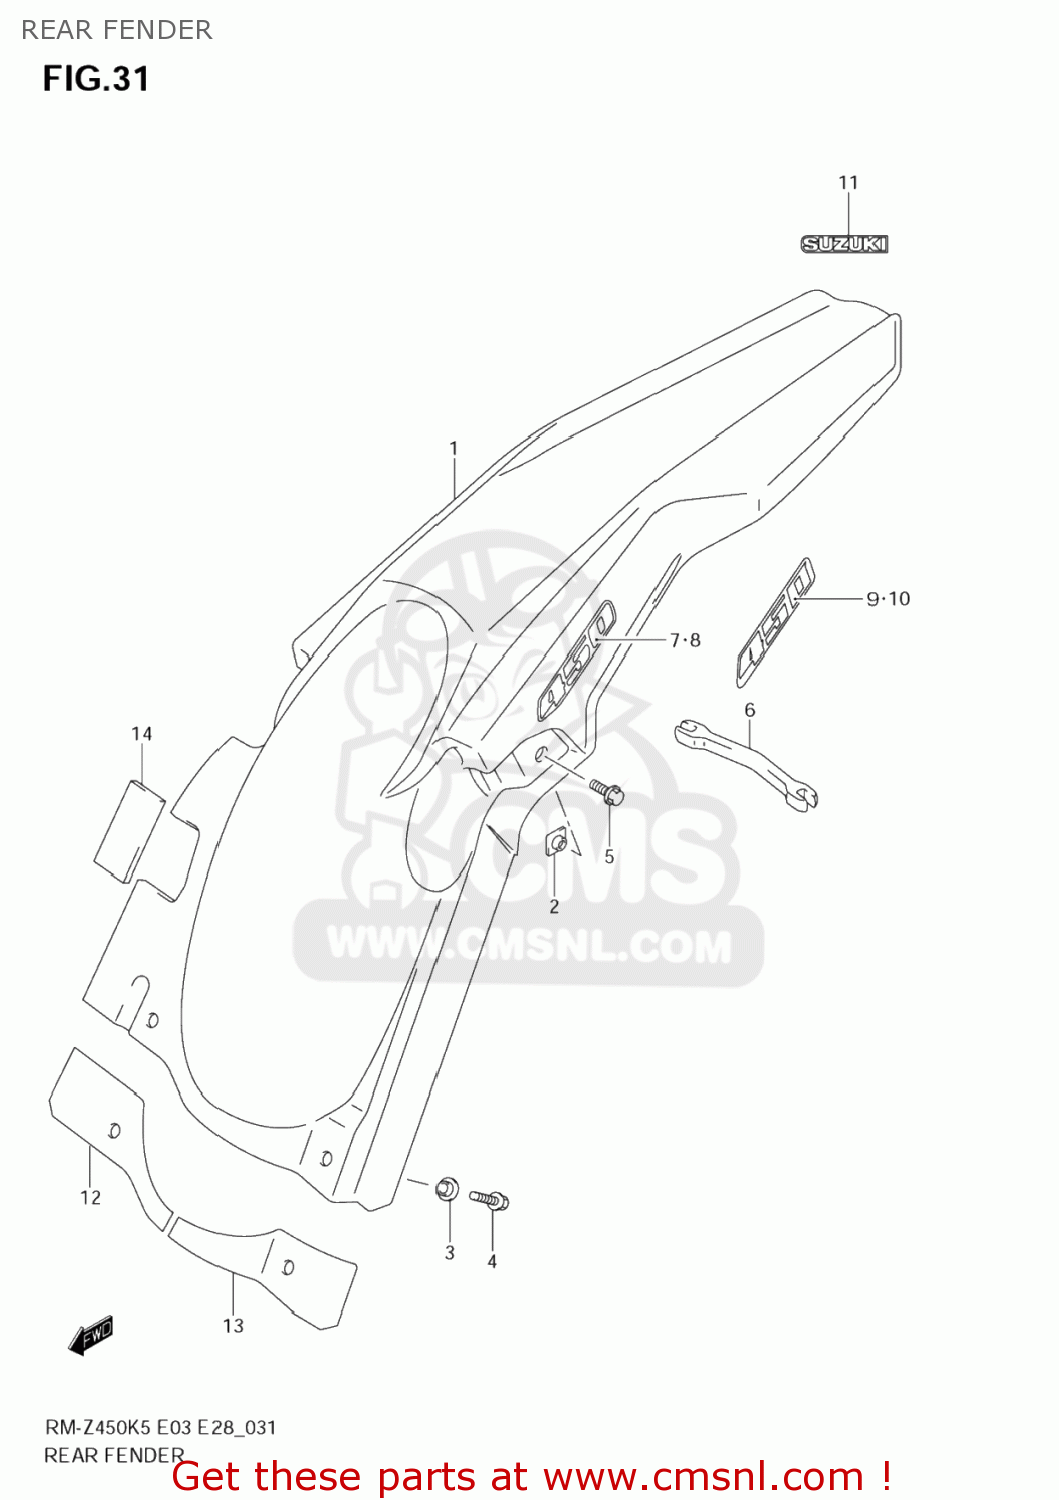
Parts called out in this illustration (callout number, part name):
1	FENDER,RR
2	NUT
3	WASHER,RR BRAK
4	BOLT,6X20
5	BOLT(6X16)
6	OPEN SPANNER(6.4X6.8)
7	TAPE,RR FENDER,R
8	TAPE,RR FENDER,L
9	TAPE,RR FENDER,R
10	TAPE,RR FENDER,L
11	EMBLEM,SUZUKI
12	CUSHION,RR FENDER,R
13	CUSHION,RR FENDER,L
14	CUSHION,RR FENDER,R
